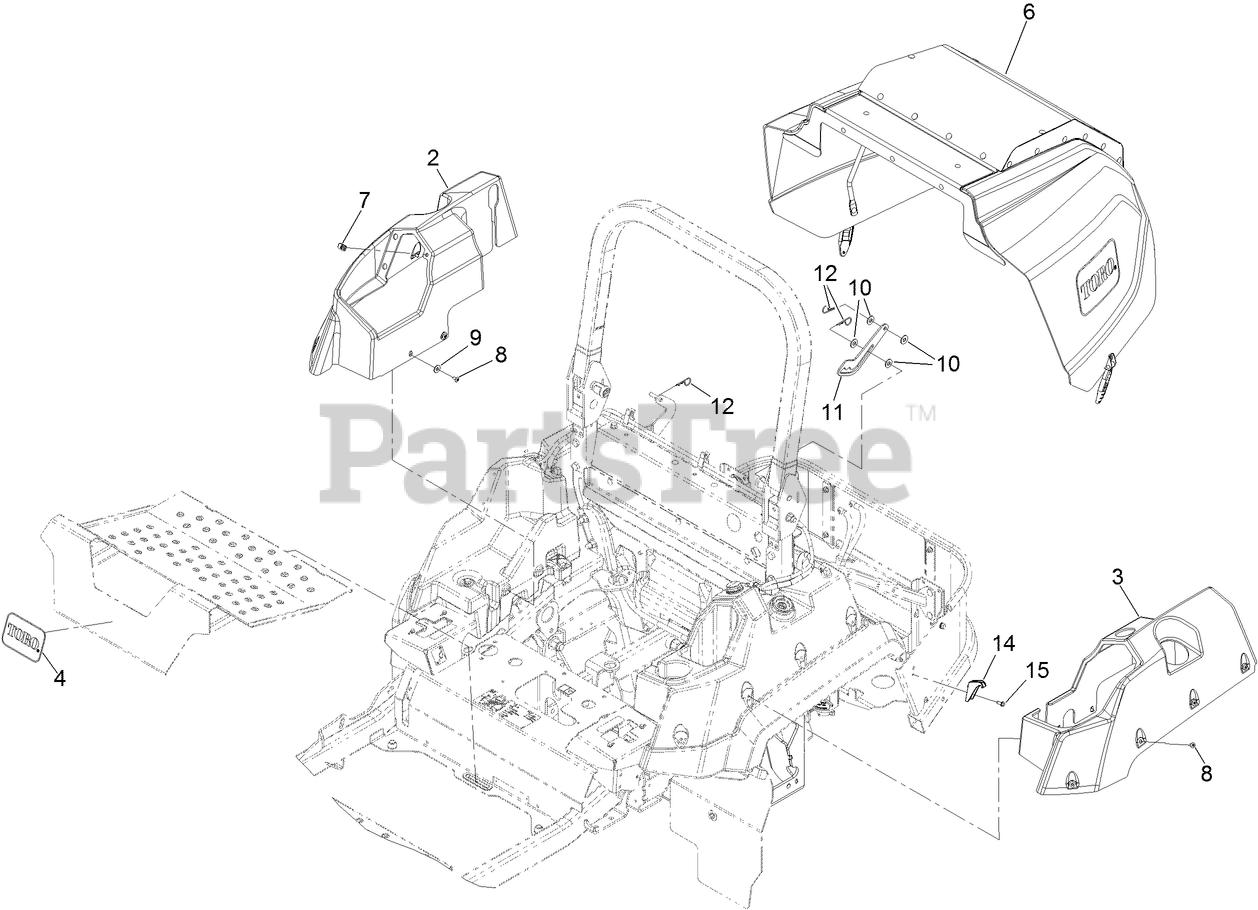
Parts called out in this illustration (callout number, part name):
2	COVER-TANK, RH
3	COVER-TANK, LH
4	DECAL
6	HOOD ASM
8	SCREW-TORX
9	WASHER-FLAT
10	WASHER-FLAT
11	PROP-HOOD
12	PIN-COTTER, HAIR
14	LATCH-CATCH
15	SCREW-HWH
